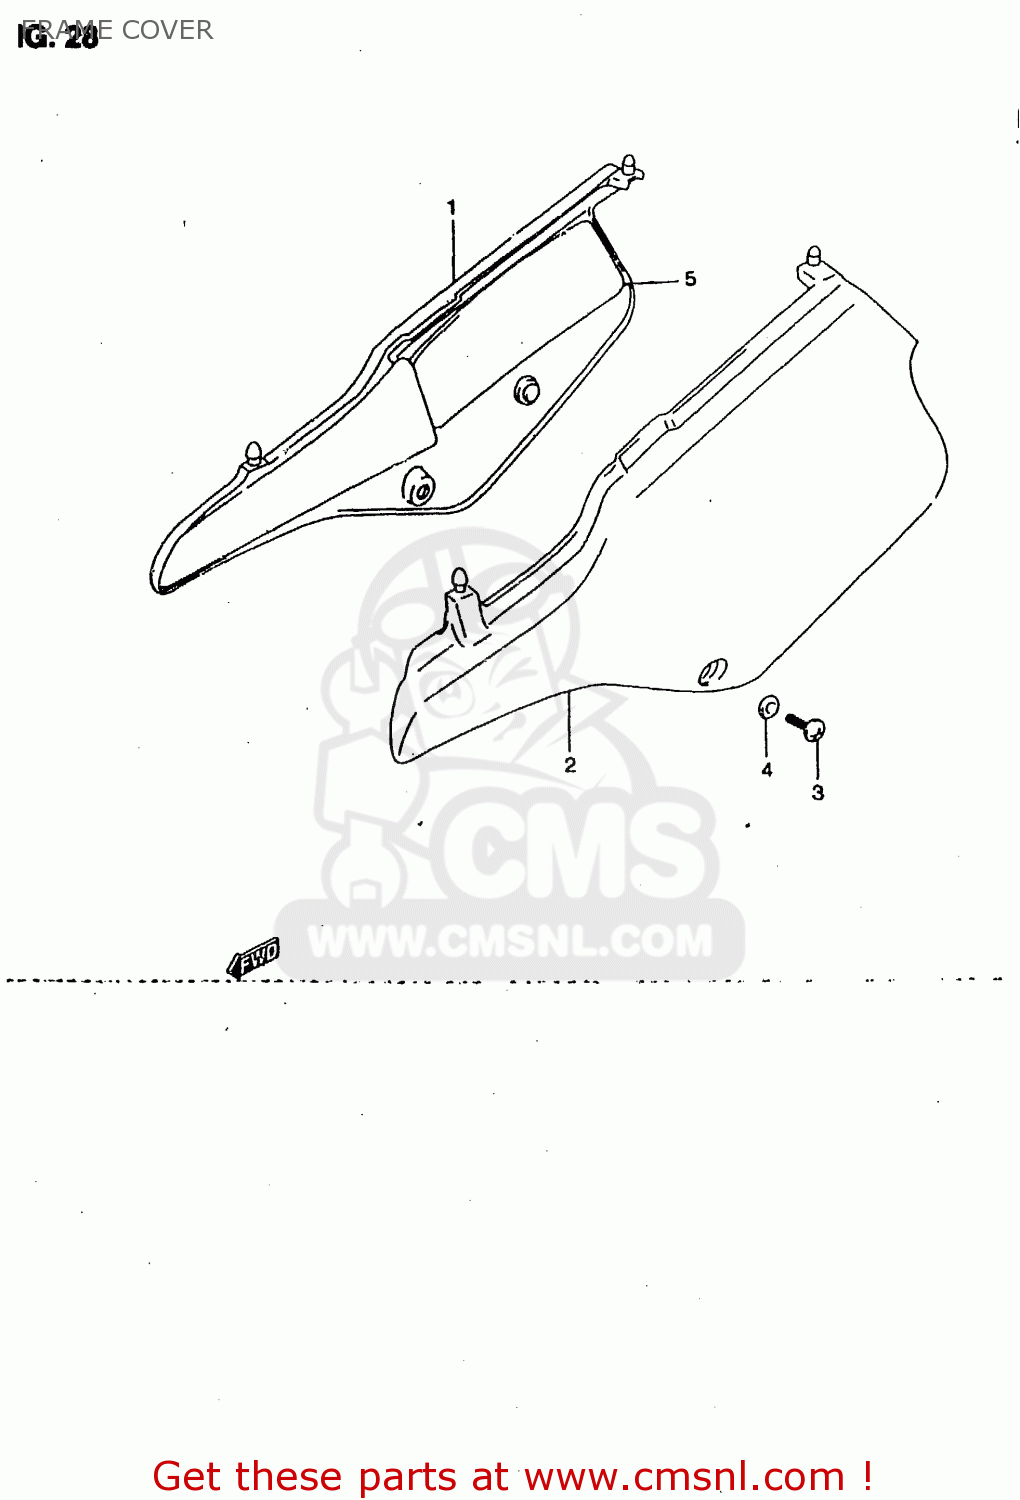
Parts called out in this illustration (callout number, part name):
1	COVER, FRAME RH
2	COVER, FRAME LH
3	SCREW 6X16
4	WASHER(6.5X18X1.6)
5	SHIELD, FRAME COVER, R
